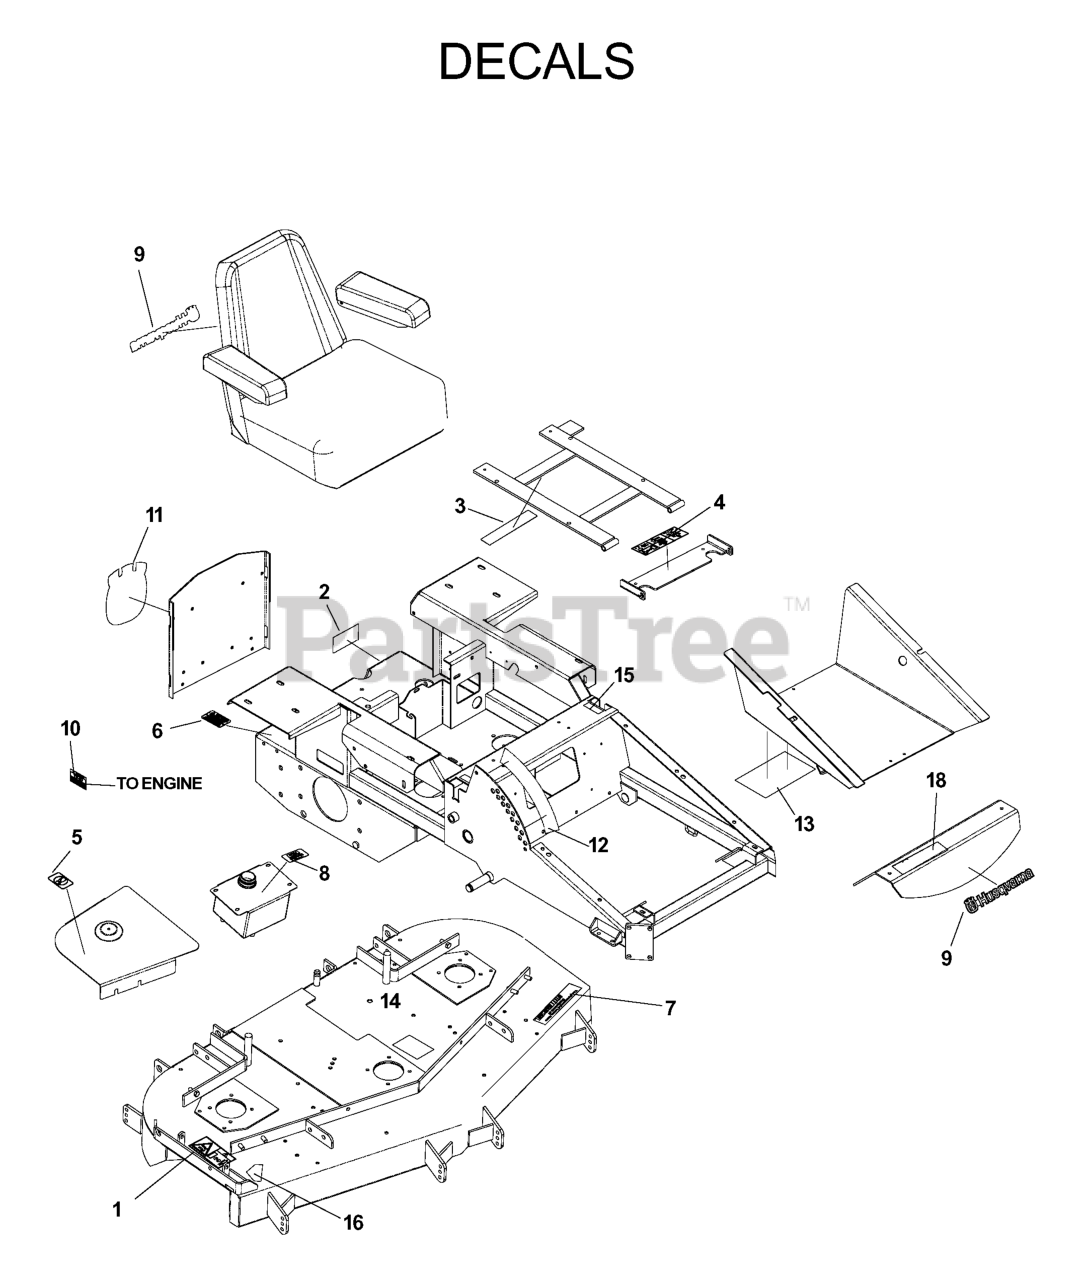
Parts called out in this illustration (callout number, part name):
1	DECAL, EURO SEVERING
2	DECAL, BELT DRIVE
3	EURO DECAL-BATTERY WARNIN6
4	DECAL, EURO WARNING
5	DECAL, NO STEP
6	DECAL, PROP. 65
7	DECAL, NASCAR
8	DECAL, MOBIL 1
9	DECAL, HUSQVARNA LOGO 9.25"
10	DECAL, EXHAUST
11	DECAL, LGE CROWN 7X6"
12	HEIGHT ADJ DECAL
13	SERVICE DECAL
14	BELT ROUTING DECAL
15	DECAL, MOTION CONTROL
16	DECAL, CPSC
17	DECAL, FUEL VALVE
18	DECAL - IZIZ4218
539107744	DECAL, IZ4818
539107745	DECAL - IZ4821
539107746	DECAL, IZ5223
